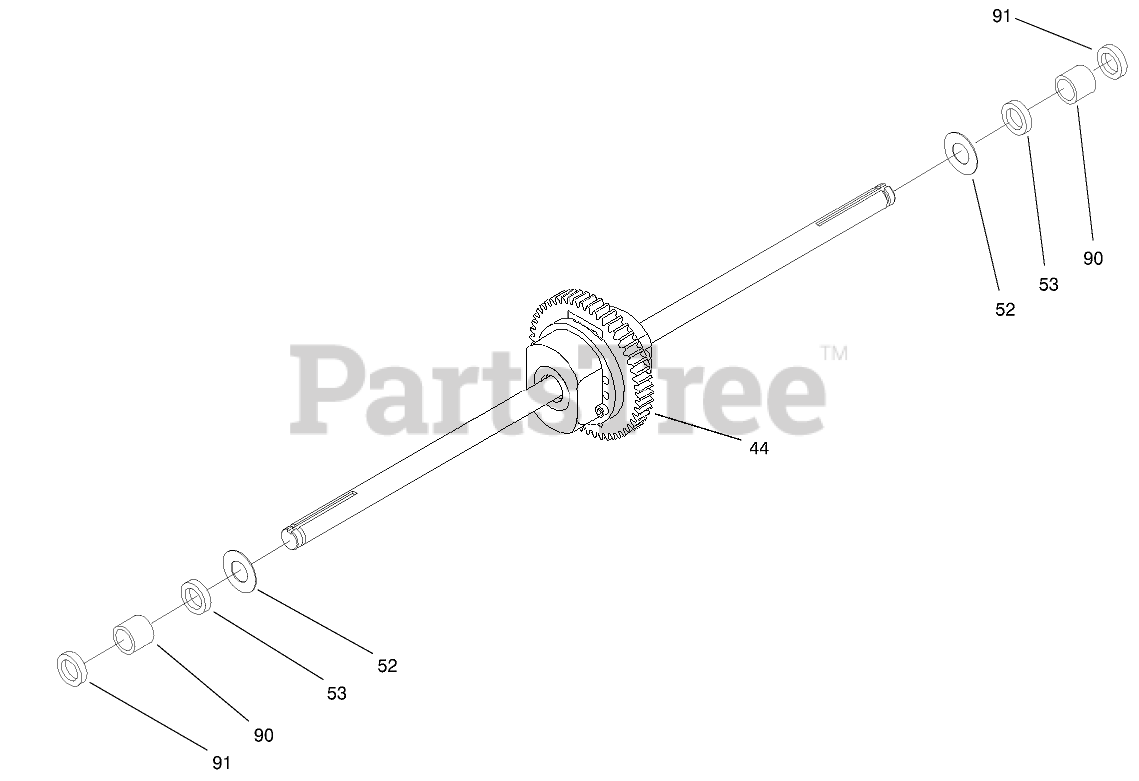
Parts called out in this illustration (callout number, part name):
44	Differential ASM
52	WASHER
53	SEAL
90	SLEEVE - BEARING
91	SEAL - WIPER
